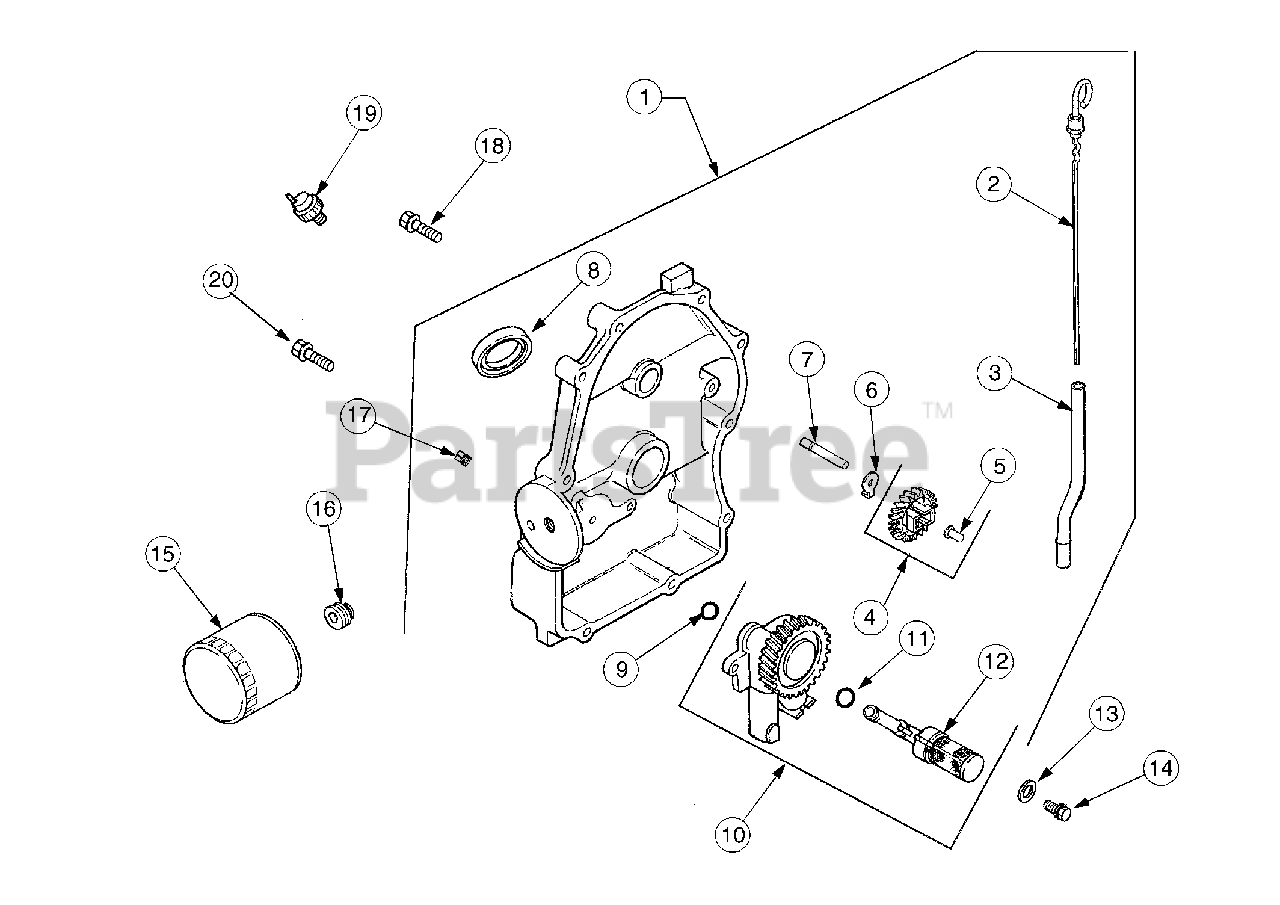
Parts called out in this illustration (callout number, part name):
1	Plate Assy, Closure
3	Tube Kit, Dipstick
4	Kit, Governor Gear
5	Pin, Governor Regulating
6	Tab, Locking
7	Shaft, Governor Gear
8	Seal, Oil (PTO end)
10	Oil Pump Assy
11	O-Ring, Oil Pick-up
12	Pick-up, Oil
13	Washer, Plain
14	Screw, Hex Flange, M6 x 1.0 x 25
15	Filter, Oil
16	Nipple, Oil Filter
17	Plug, Pipe 1/8"
18	Screw, Hex Flange, M8 x 1.25 x 45
19	Switch, Pressure
20	Screw, Hex Flange, M8 x 1.25 x 45
